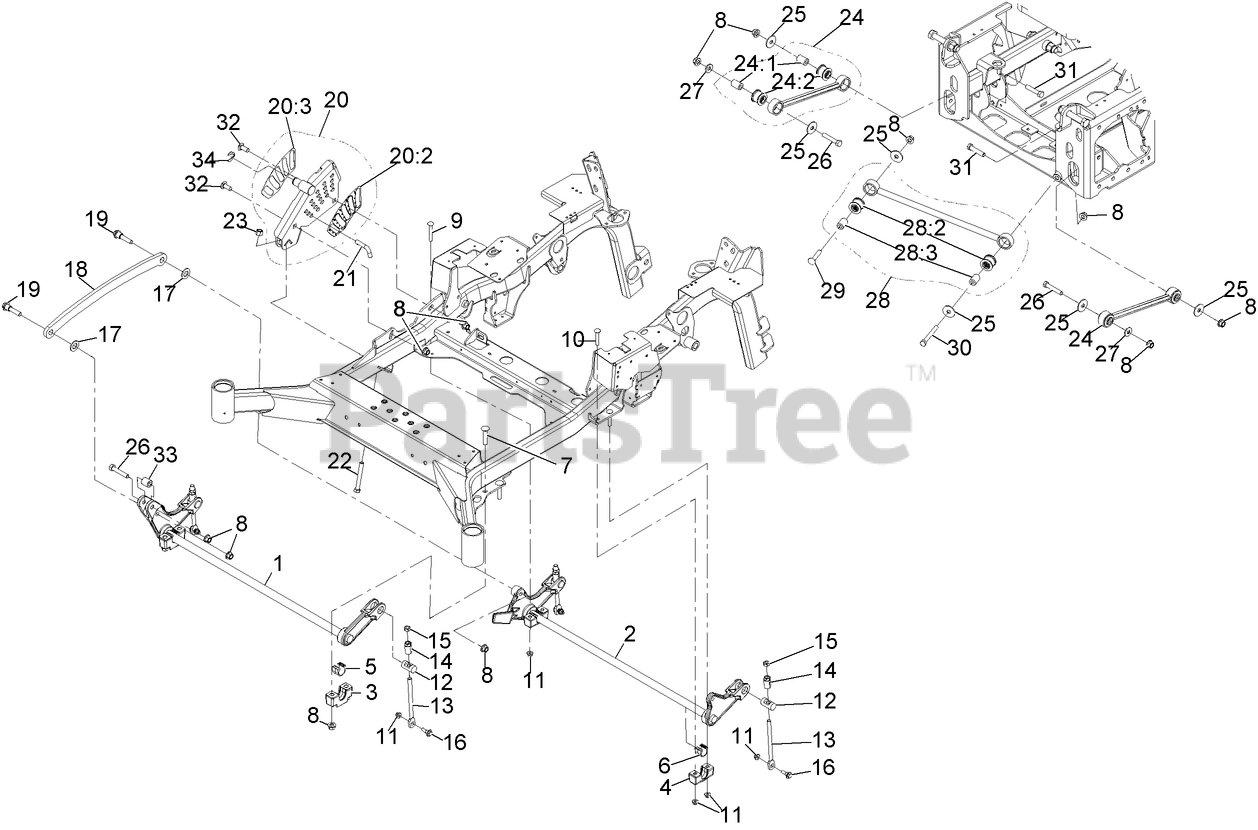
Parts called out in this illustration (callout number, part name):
1	DECKLIFT-FRONT
2	LIFT-DECK, REAR
3	SUPPORT-CROSS SHAFT, BEARING
4	SUPPORT-CROSS SHAFT, BEARING REAR
5	BEARING-CROSS SHAFT, FRONT
6	BEARING-CROSS SHAFT, REAR
7	BOLT-CARR
8	NUT-LOCK
9	SCREW-CARR
10	SCREW-CARR
11	NUT-HF, NI
12	TRUNNION
13	LINK-ADJUSTER, DECK LIFT
14	ADJUSTER-LIFT, DECK
15	NUT-JAM
16	SCREW-SHOULDER, HHF
17	WASHER-FLAT
18	LINK-LIFT, DECK
19	SCREW-HHF, SHOULDER
20	HOC ASM
20:2	DECAL-HEIGHT OF CUT
20:3	DECAL-HEIGHT OF CUT, OUTER
21	PIN-HOC
22	BOLT-TAP
23	NUT-LOCK, NI
24	DECK STRUT ASM 85A
24:1	SPACER
24:2	BUSHING-RUBBER
25	WASHER-THRUST
26	SCREW-HH
27	WASHER-SPRING
28	PANHARD ROD ASM
28:2	BUSHING-SUSPENSION, RUBBER
28:3	SPACER
29	SCREW-CARR
30	SCREW-HH
31	SCREW-HH
32	SCREW-CARR, SHORT NECK
33	SPACER-PIVOT
34	RING-RETAINING
